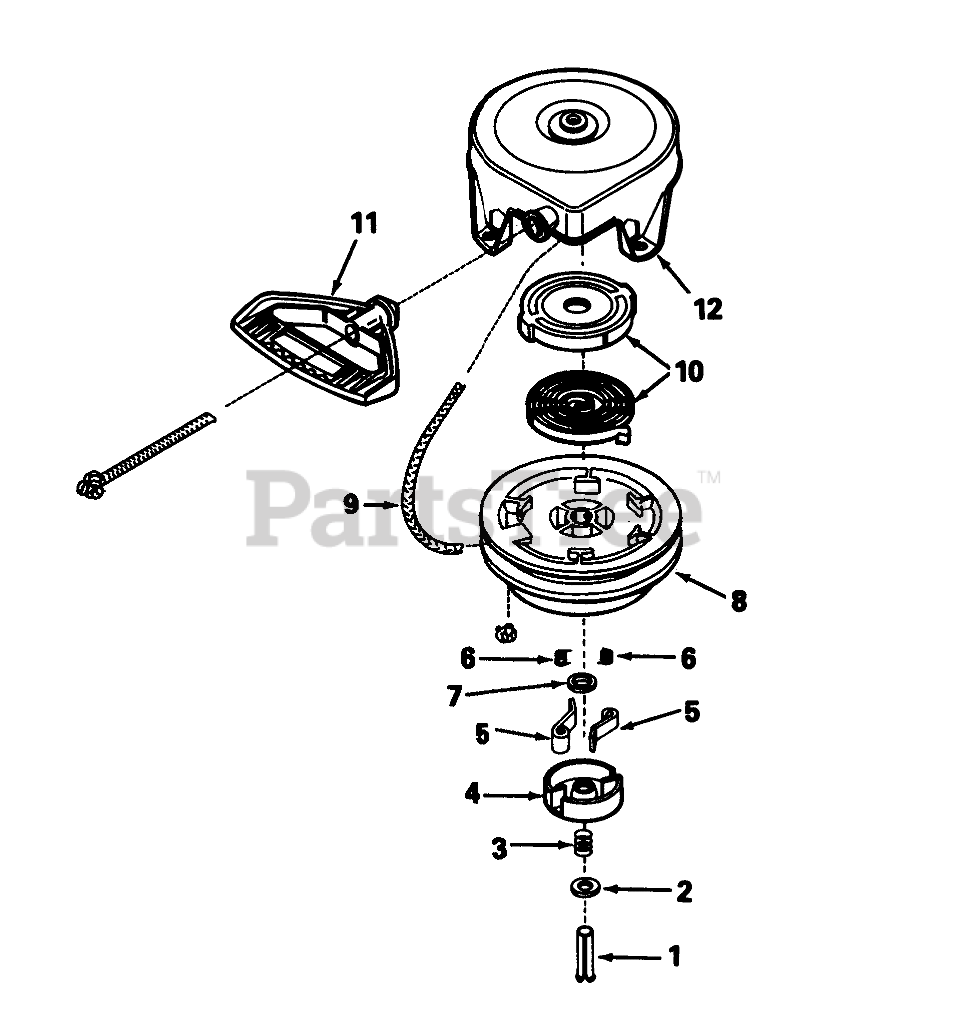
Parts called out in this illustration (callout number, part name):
1	Pin-Spring (Incl. Ref. #7)
3	Brake Spring
4	Retainer
5	Dog-Starter
6	Spring-Dog
9	Rope-Starter
10	Spring & Keeper Assy.
11	Handle-Starter, Mitten Grip
12	Housing Assy., Starter
